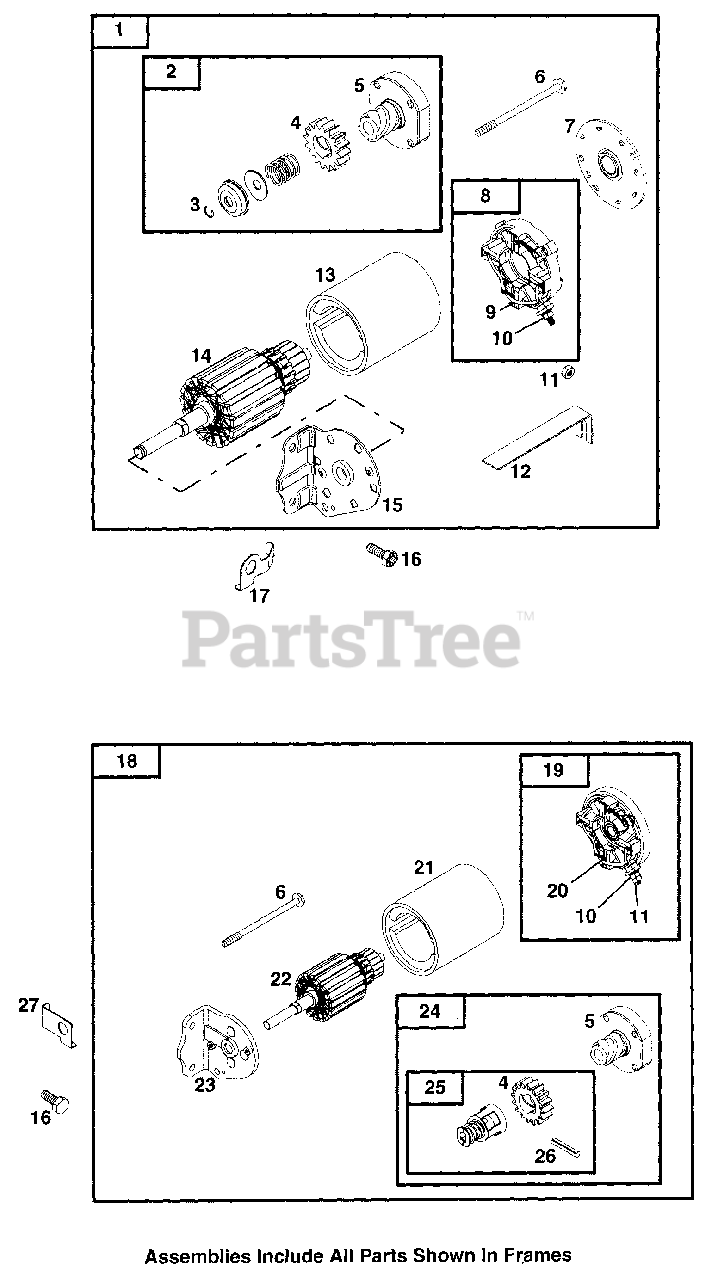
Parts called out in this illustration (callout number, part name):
1	Motor-Starter
2	Drive-Starter
3	Ring-Retaining
4	Gear-Pinion
5	Clutch-Drive
6	Bolt (Starter Motor)
8	Retainer-Brush
10	Nut (Brush Retainer)
11	Nut (Brush Retainer)
12	Starter Strap
13	Housing-Starter
14	Armature-Starter
15	Cap-Drive
16	Screw (Drive Cap)
21	Housing-Starter
22	Armature-Starter
24	Drive-Starter
25	Kit-Gear
26	Pin-Roll
